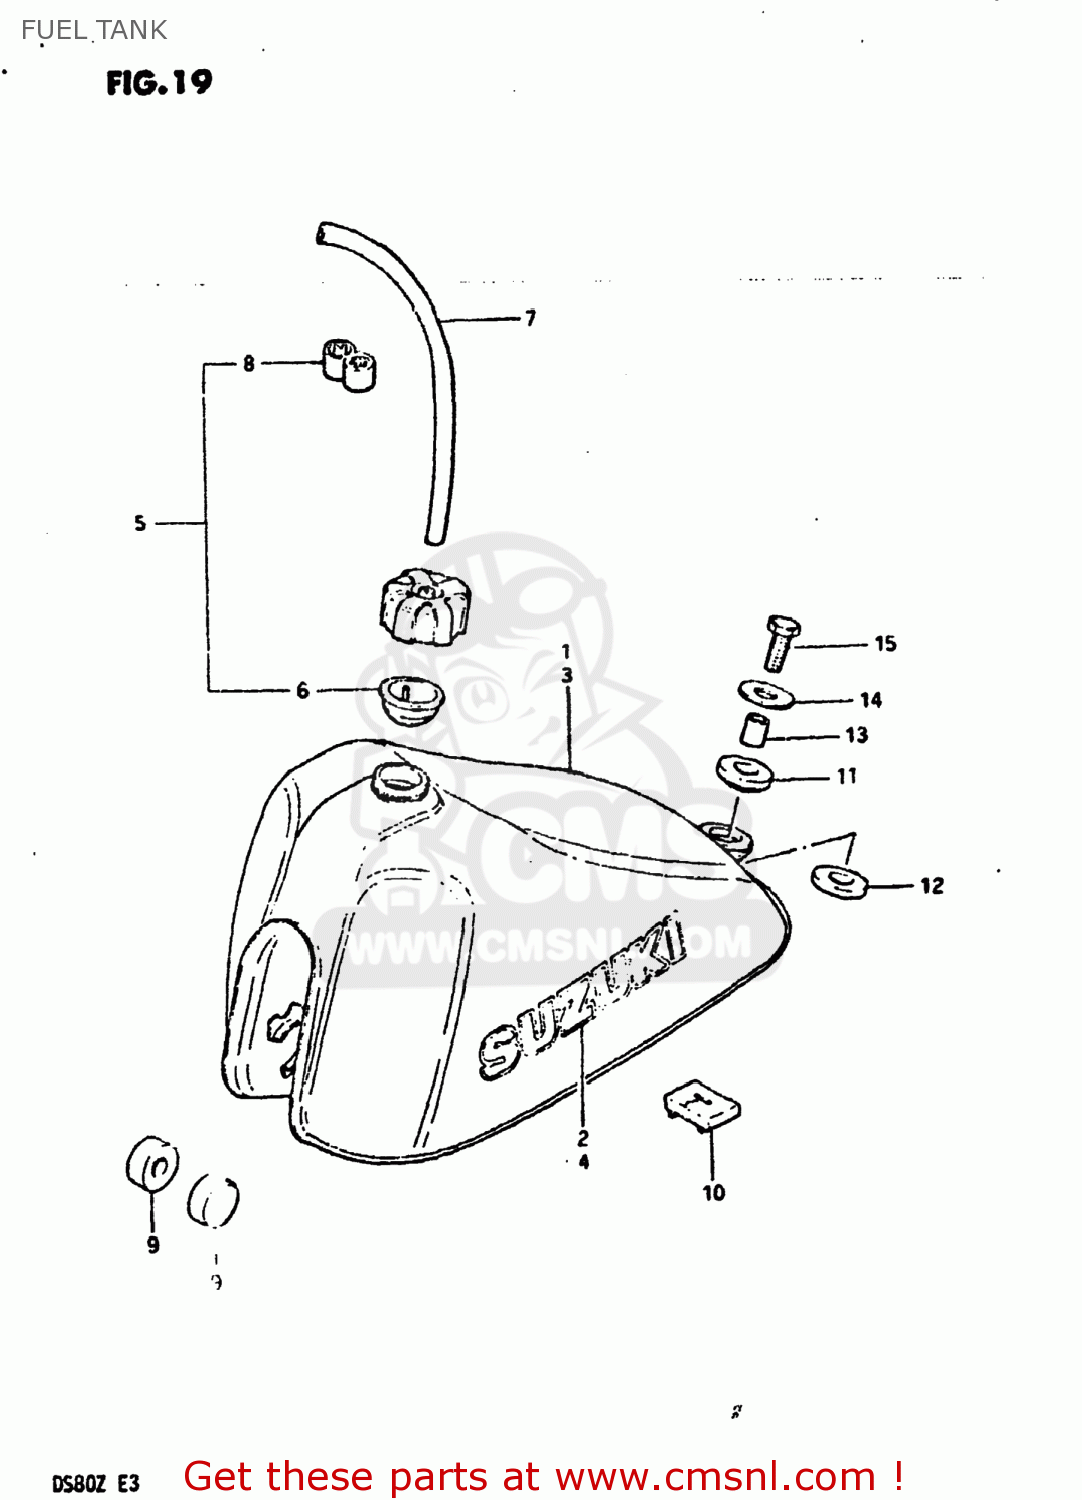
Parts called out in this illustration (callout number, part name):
1	TANK ASSEMBLY,FUEL
2	EMBLEM
3	TANK ASSEMBLY,FUEL
4	EMBLEM(BLACK)
5	CAP ASSEMBLY,FUEL TANK
6	GASKET,FUEL TANK CAP
7	HOSE
8	CLAMP,FUEL TANK BREATHER HOSE
9	CUSHION
10	CUSHION,FUEL TANK
11	CUSHION
12	CUSHION
13	SPACER (8.8X12X13.5)
14	WASHER (8.5X29X1.6)
15	BOLT
